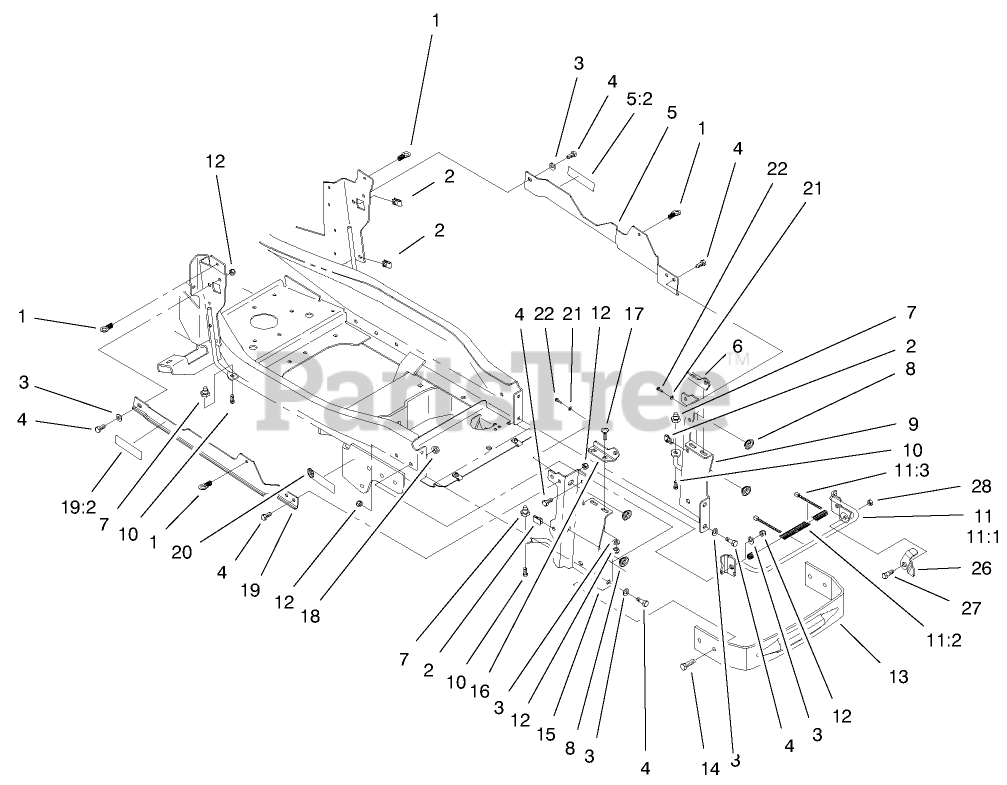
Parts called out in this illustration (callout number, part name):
1	LATCH ASM
3	WASHER-PLAIN
4	SCREW-HH
5	SUPPORT / DECAL ASM
5	SUPPORT ASM
5:2	DECAL-WARNING
5:2	DECAL - WARNING
6	BRACKET-HINGE, LOWER LH
7	MOUNT-SIDEPANEL
8	GROMMET
10	SCREW-PLASTITE
11:2	COVER-BRACE
11:3	TIE-CABLE
12	NUT-LOCK, NI
14	SCREW-HH
15	SUPPORT-HOOD, RH
16	BRACKET-HINGE, LOWER RH
17	SCREW-CARR
18	NUT-LOCK, NI
19	SUPPORT ASM
19:2	DECAL-WARNING
19:2	DECAL - WARNING
20	DECAL-ATTACH A-MATIC
21	WASHER-FLAT
22	SCREW-THD FORM, HWH
26	LEVER-PROP, HOOD
27	BOLT-SHOULDER,HFH
28	NUT-LOCK, NI
